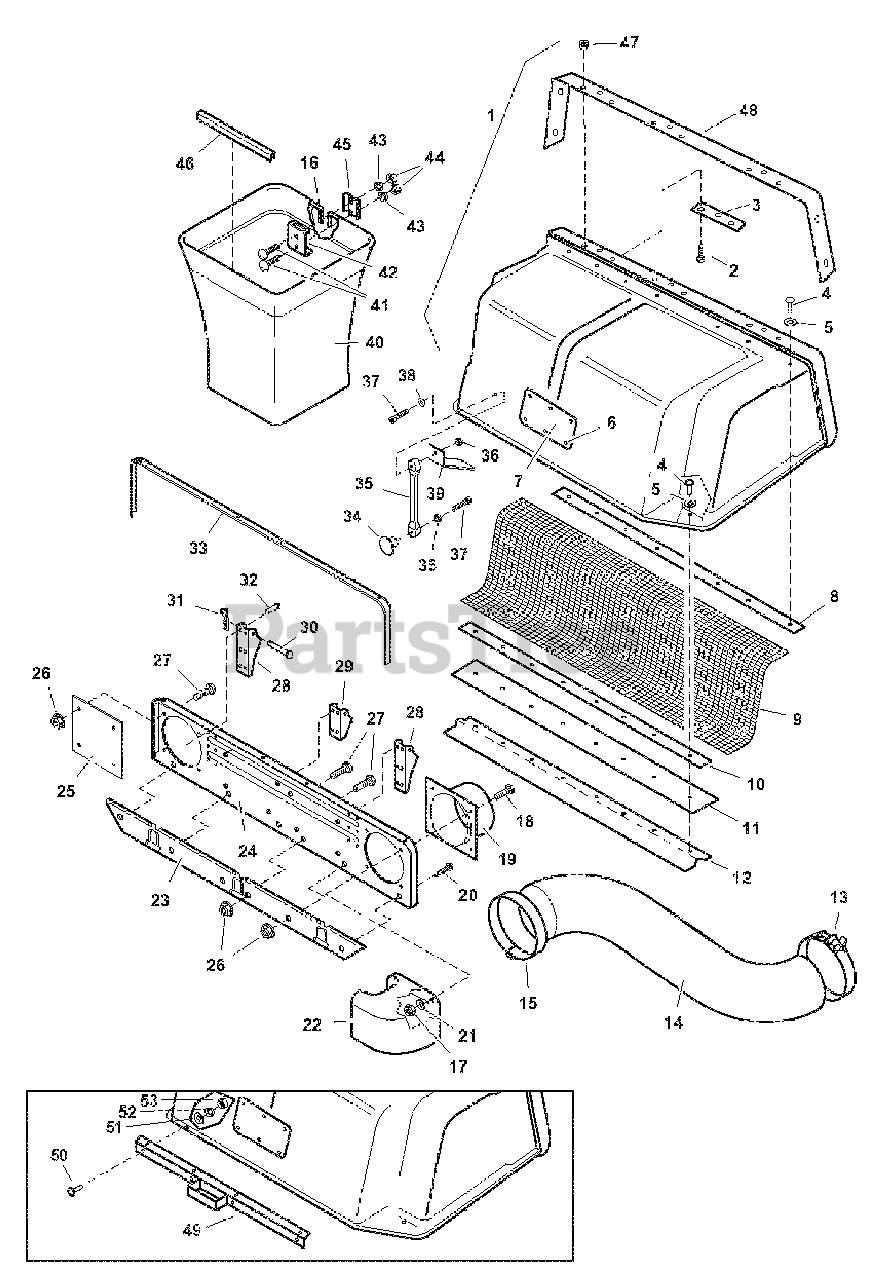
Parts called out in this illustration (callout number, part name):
1	COVER & SCREEN ASSEMBLY
2	BOLT, 1/4-20 x 3/4
2	HHCS, 1/4-20 X 0.625, GR5, ZINC/CLEAR
3	HINGE ASSEMBLY
4	RIVET
5	WASHER
6	CLIP, Canoe
7	DECAL, Safety
8	CLAMP
9	SCREEN
10	CLAMP, Seal
11	SEAL
12	ANGLE, Screen
13	HOSE CLAMP, Lower
14	HOSE, FLEXIBLE, 7" DIA. X 58"
15	HOSE CLAMP, Upper
16	HOOP, Bag
17	NUT, 5/16-18 Hex Nylon Lock
18	BOLT, 5/16-18 X 1 GD5 YZ
19	HOSE ADAPTER
20	CAPSCREW, Taptite, 1/4-20 x 1/2
21	WASHER, 5/16" SAE
22	DEFLECTOR
23	CHANNEL ASSEMBLY
24	PLATE ASSEMBLY
25	INLET COVER
26	NUT, 5/16-18 Hex Small Serrated Flange
27	BOLT, 5/16-18 X 3/4 GD5
28	HINGE
29	HINGE
30	PIN, 3/8 x 2-3/4
31	PIN, Hair
33	SEAL
34	KNOB
35	RUBBER STRAP
36	NUT, #10-32 Hex Nylon Lock
37	SCREW, #10-32 x 1-1/2
38	WASHER, 3/16" USS
39	COVER SUPPORT
40	BAG, Grass (Black)
41	CARRIAGE BOLT, 5/16-18 x 3/4
42	HANGER
43	WASHER, 5/16" Lock
44	NUT, 5/16-18 HEX
45	CLAMP
46	TUBE CLIP, Grass Bag
47	NUT, 1/4-20 Hex Serrated Flange
48	HINGE STIFFENER
49	COVER HANDLE
50	SCREW, #8-32 x 1/2
51	WASHER, #8 SAE
52	WASHER, Lock, #8
53	NUT, Hex, #8-32
